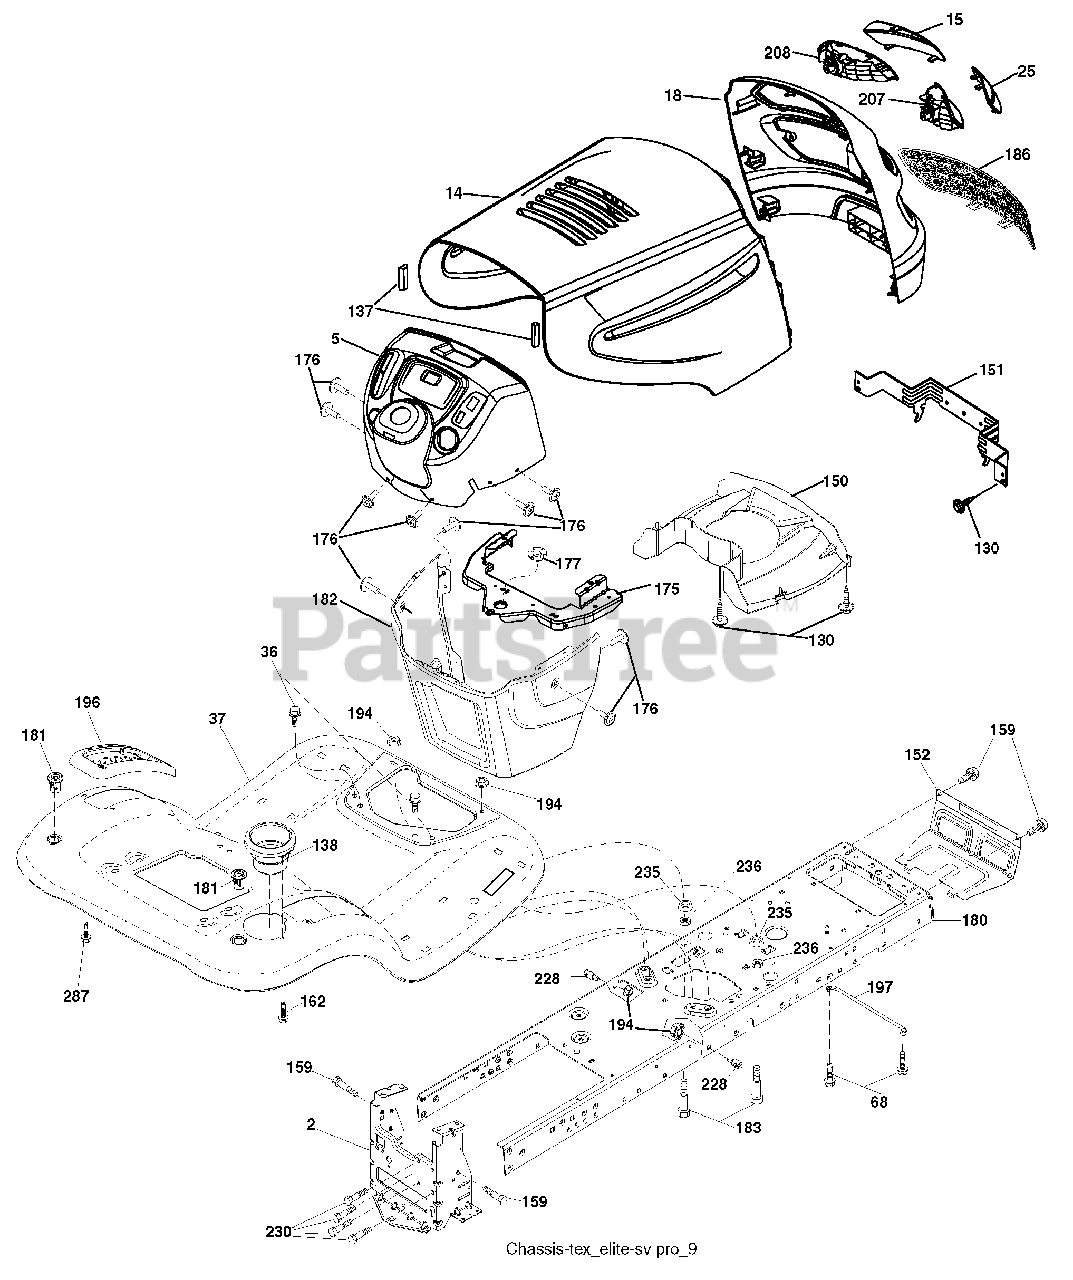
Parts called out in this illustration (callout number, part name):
2	Drawbar
5	Dash
14	Hood
15	Lens Grille LH
18	Grille
25	Lens Grille RH
36	Screw 5/16-18 x 3/4
37	Fender
68	Screw Thdrol. 5/16-18 x 1/2
130	Screw #10 x 0.750 BOS Thread
137	Bumper Hood
138	Cupholder
150	Duct Heat Hood
151	Bracket Pivot
152	Shield Browning/Debris
159	Screw Hexwsh. Thdrol. 3/8-16 x 3/4
162	Screw Hex Wsh. Hi-Lo 1/4 x 1/2
175	Crossmember
176	Screw 10-24 x 5/8 Wshd. Qdrx.
177	Bushing Steering
181	Bushing Mtg. Fender Crgo.
182	Dash Lower
183	Bolt Fin Hex 5/16-18 x 1-1/4
194	Nut Lock Hex Flange 5/16-18
196	Console Asm. Deck Lift
197	Rod Pivot Chassis
207	Bezel Grille RH
208	Bezel Grille LH
228	Stud Fastener
230	Bolt Shoulder 5/16-18
235	Spacer Fender
236	Nut Center Lock 5/16-18
287	Screw Hex Washead
